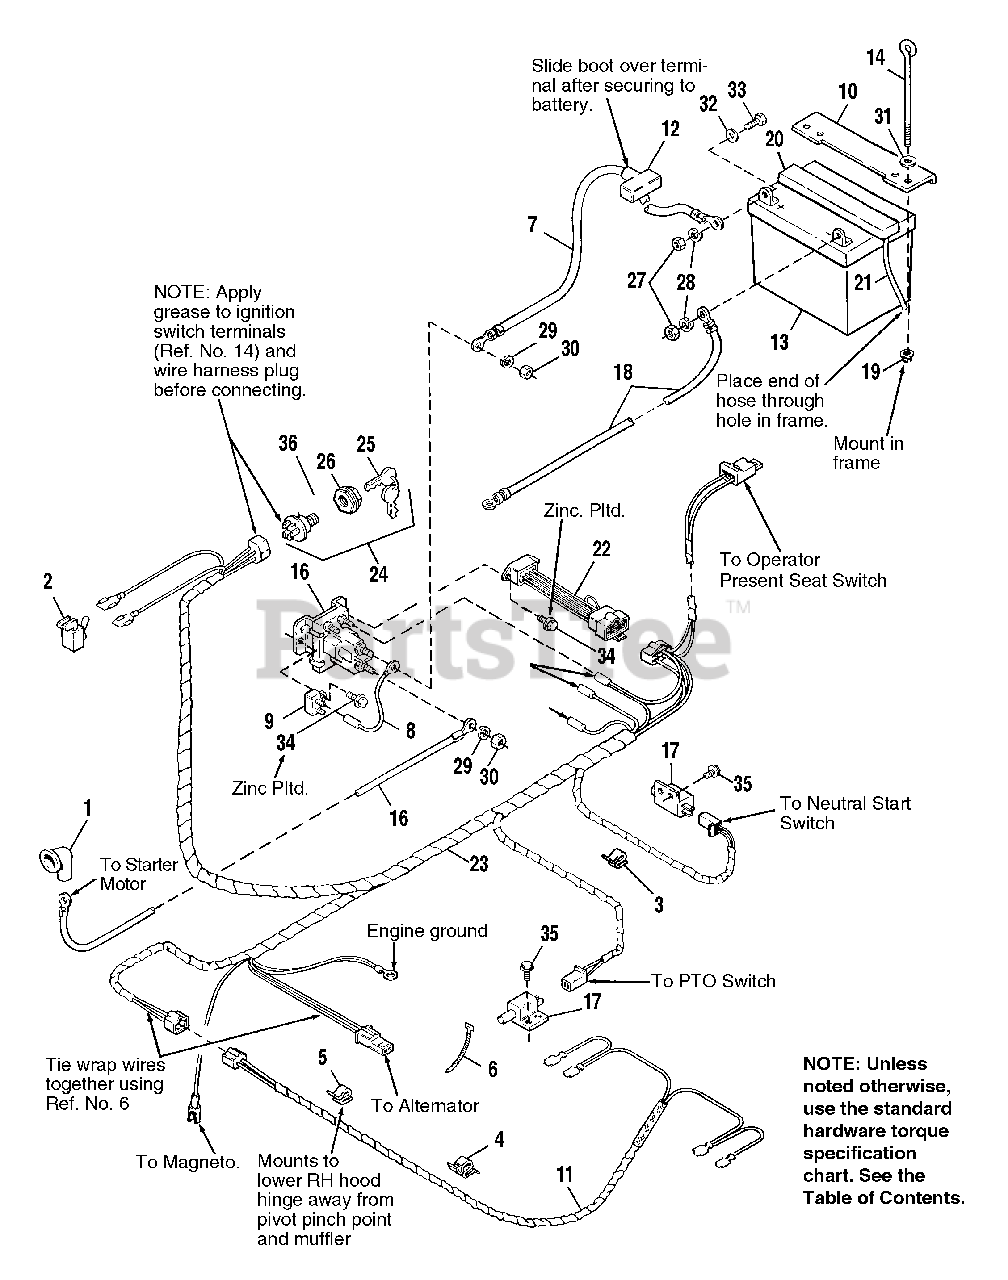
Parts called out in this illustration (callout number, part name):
1	COVER, Terminal
2	SWITCH, Headlight
4	CLIP, Cable
5	CLIP, Wire
6	TIE, Self-Locking
7	CABLE, Ground
9	CIRCUIT BREAKER
10	HOLD DOWN, Battery
11	WIRE ASSY., Headlights
12	BOOT, Insulator
14	ROD, Battery Hold Down
17	SWITCH, PTO and Neutral
18	CABLE, Ground
19	NUT, Retainer, 1/4-20
20	VENT CAP, Battery
21	HOSE, Drain
22	MODULE, DSI Interlock, Seat Switch
23	HARNESS, Wiring
24	SWITCH
25	KEY SET (2 keys)
26	ADAPTER, Nut
27	NUT, Hex, 1/4-20
28	LOCKWASHER, 1/4
29	LOCKWASHER, 5/16
30	NUT, Hex, 5/16-24
31	WASHER, 9/32
32	WASHER, 1/4 I.D.
33	CAPSCREW, Hex Hd., 1/4-20 x 3/4
34	SCREW, Taptite, 1/4-20 x 5/8, Zinc Pltd.
35	SCREW, Taptite, #10-24 x 1/2
36	LOCKWASHER, Internal Tooth, 5/8 (Thin)
